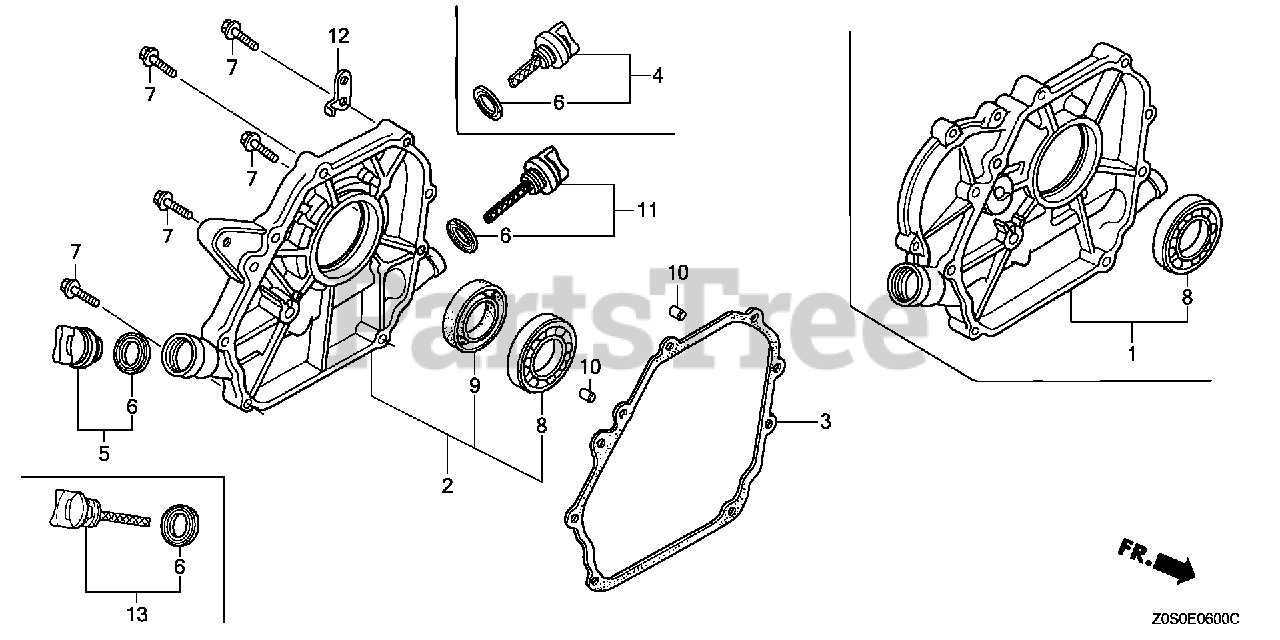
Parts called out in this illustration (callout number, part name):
2	COVER ASSY., CRANKCASE
3	GASKET, CASE COVER
5	CAP ASSY., OIL FILLER
6	GASKET, OIL FILLER CAP
7	BOLT, FLANGE (6X28) (CT200) Use up to Engine SN 1530314.
8	BEARING, RADIAL BALL (62/22)
9	OIL SEAL (22X41X6)
10	PIN A, DOWEL (8X14)
11	CAP ASSY., OIL FILLER
